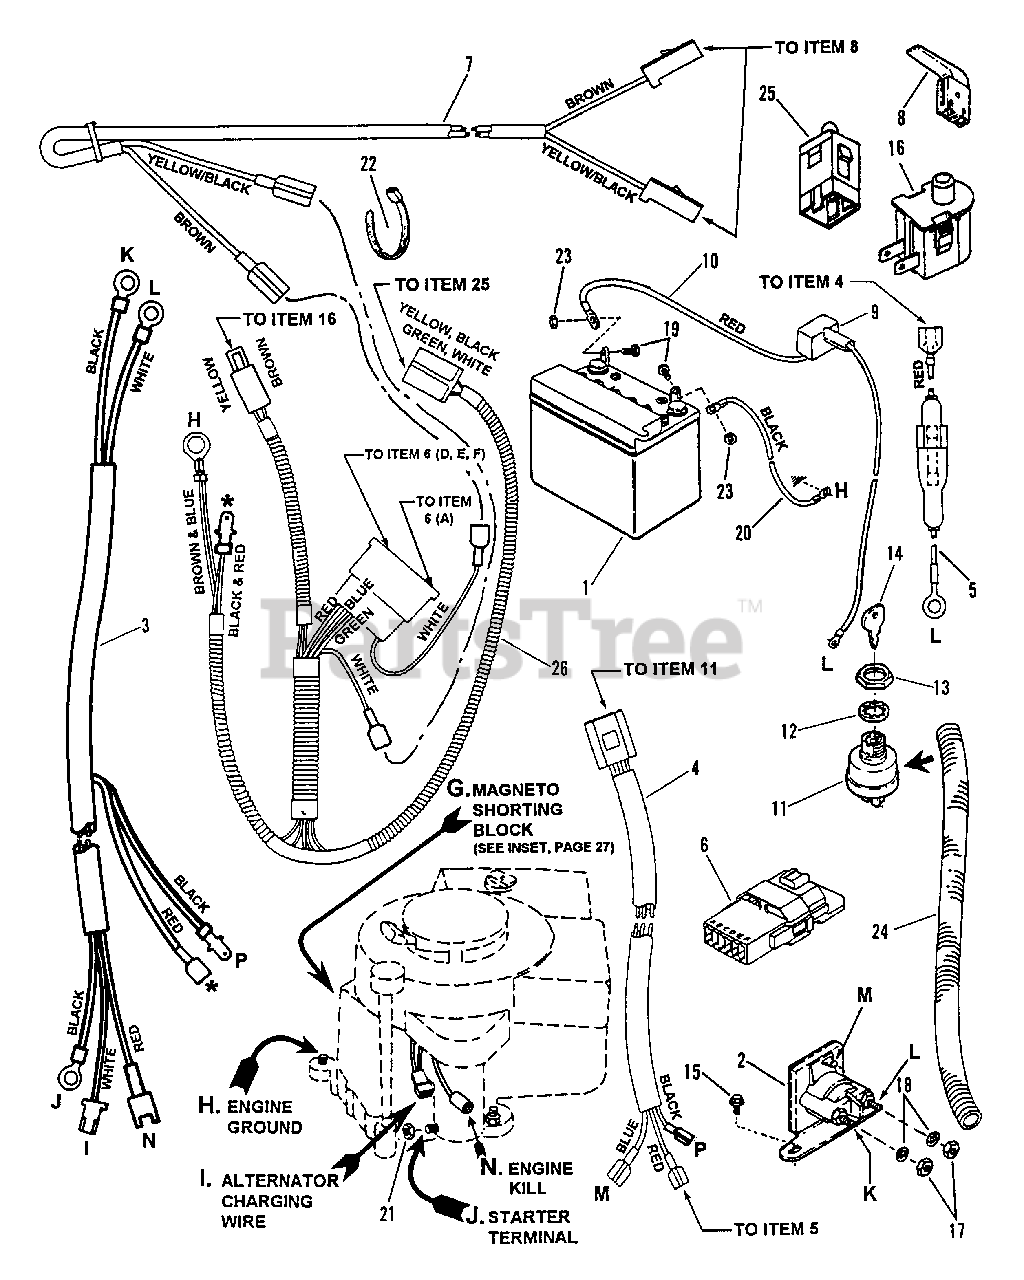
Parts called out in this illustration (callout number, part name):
1	KIT, 12V Dry Charge Battery
2	SOLENOID
3	HARNESS, Starter Wiring (Tecumseh)
4	HARNESS, Ignition Wiring
5	HOLDER, Fuse
6	INTERLOCK Module (Kohler/Tecumseh)
7	HARNESS, Deck Interlock Wiring
8	SWITCH, Deck Interlock
9	COVER, Battery Cable
10	CABLE, Positive (Red)
11	SWITCH, Ignition (Includes keys #11138)
12	WASHER, 5/8 Internal Tooth Lock
13	NUT, 5/8-32 Hex
14	KEY, Switch
15	SCREW, 1/4-20 x 1/2" Self-Tapping
16	SWITCH
17	NUT, 1/4-20 Hex
18	WASHER, 1/4 Internal Tooth Lock
19	SCREW, 1/4-20 x 5/8" Hex Head Cap
20	CABLE, Negative
21	NUT, 1/4-20 Hex
22	TIE, 7" Long Cable
23	NUT, 1/4-20 Hex Lock
24	CONDUIT
25	SWITCH, Traction
26	HARNESS WIRE
